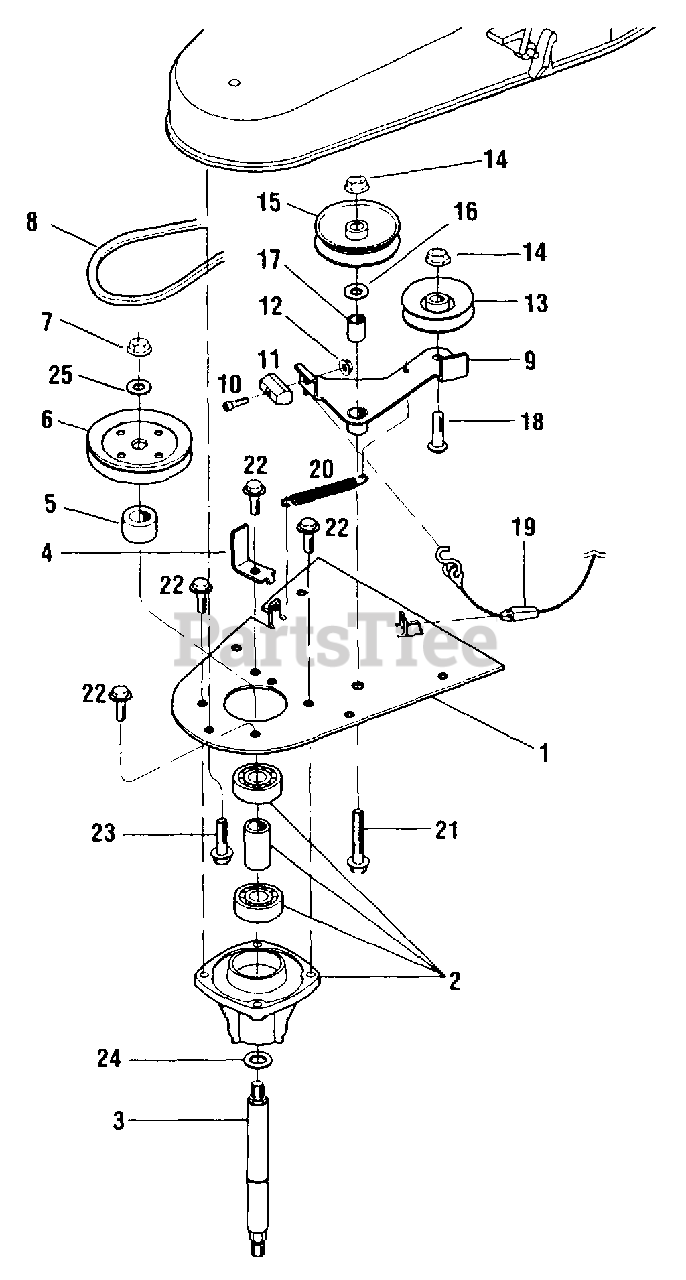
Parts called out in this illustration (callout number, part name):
1	Spindle Mounting Plate
2	Spindle Assembly
3	Spindle Shaft Assembly
4	Belt Guide
5	Spindle Spacer
6	Spindle Pulley
7	Hex Flange Nut, 1/2-13
8	V-Belt, L453
9	Idler Arm/Brake Shoe Assembly
10	Socket Hd Capscrew, 10-24 x 3/4
11	Brake Shoe
12	Hex Lock Nut, 10-24
13	V-Groove Idler Pulley
14	Hex Flange Nut, 3/8-16
15	Flat Idler Pulley
16	Washer, .88 x .382 x .275
17	Idler Arm Spacer
18	Button Hd Screw, 3/8-16 x 1-1/2
19	Control Cable
20	Idler Tension Spring
21	Hex Flange Screw, 3/8 x 16 x 2-1/4
22	Hex Flange Screw, 5/16-18 x 3/4
23	Hex Flange Screw, 5/16-18 x 1
24	Hardened Shim, 3/4 ID x 1.022 OD x .060 thick
25	Belleville Washer
